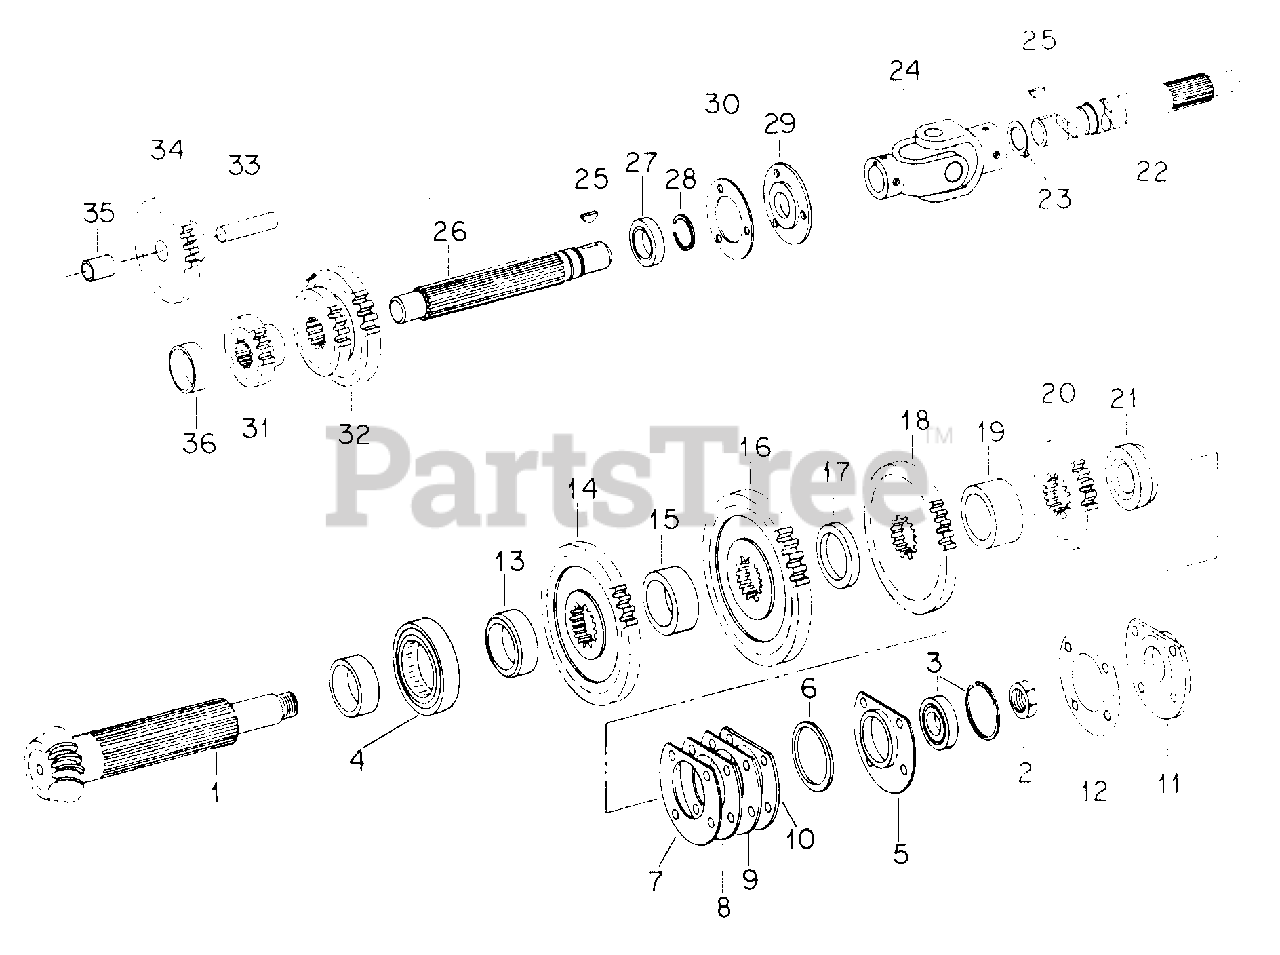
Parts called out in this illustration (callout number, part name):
1	COUNTERSHAFT, BEVEL PINION -1OT
2	NUT, COUNTERSHAFT
3	BEARING, COUNTERSHAFT
4	BEARING, COUNTERSHAFT REAR
5	RETAINER, BEARING
6	RING, RETAINER SEAL
7	SHIM, BEARING RETAINER - EXTRA LIGHT
8	SHIM, BEARING RETAINER - LIGHT
9	SHIM, BEARING RETAINER - MEDIUM
10	SHIM, BEARING RETAINER - HEAVY
11	CAP, BEARING RETAINER
12	GASKET, BEARING RETAINER CAP
13	SPACER, REV SPEED GEAR & COUNTERSHAFT BEARING
14	GEAR, REVERSE SPEED - 35T
15	SPACER, 1ST & REVERSE SPEED GEAR
16	GEAR, 1ST SPEED
17	SPACER, 1ST & 2ND SPEED GEAR
18	GEAR, 2ND SPEED - 36T
19	SPACER, 2ND & 3RD SPEED GEAR
20	GEAR, 3RD SPEED - 26T
21	SPACER, 3RD SPEED GEAR & BEARING
22	SHAFT, MAIN CLUTCH
23	RING, RETAINING
24	JOINT ASSY, UNIVERSAL
25	KEY, NO. 15 WOODRUFF
26	SHAFT, MAIN TRANSMISSION
27	BEARING, SHAFT FRONT
28	RING, BEARING LOCK
29	SEAL, SHAFT OIL
30	GASKET, SHAFT OIL SEAL
31	GEAR, 1ST AND REVERSE SLIDING (13T)
32	GEAR, 2ND AND 3RD SLIDING (16T & 26T)
33	SHAFT, REVERSE IDLER
34	GEAR ASSY, REVERSE IDLER
35	BUSHING, GEAR
36	BEARING, SPLINE SHAFT REAR
